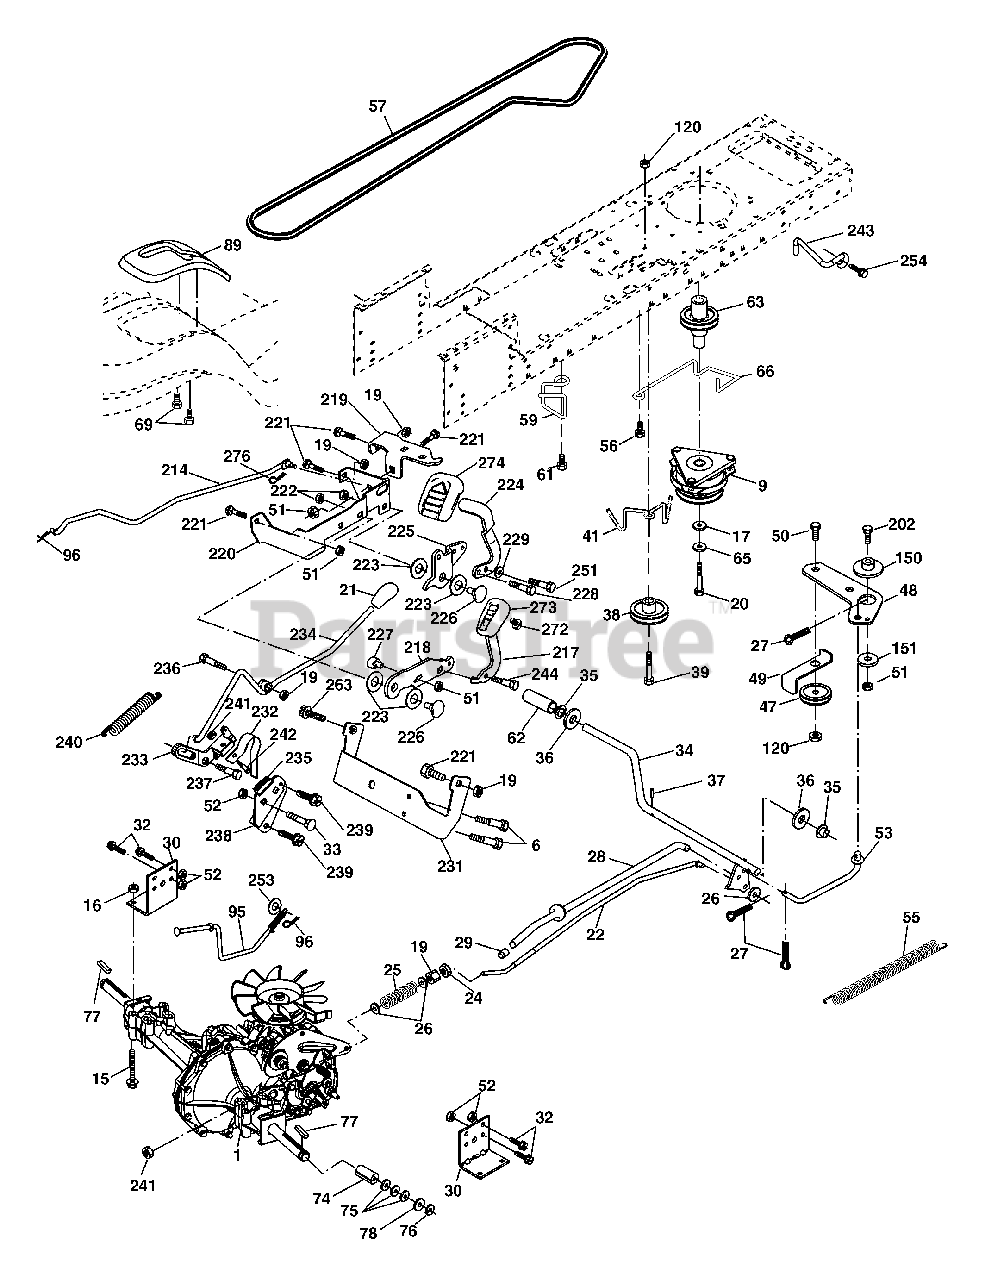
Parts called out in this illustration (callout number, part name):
1	Transaxle
6	Screw 5/16-18 x 3/4
9	Clutch Elec
15	Bolt Hex Flghd 5/16-18 Gr. 5
16	Nut Lock Hex W/Ins. 5/16-18 unc
17	Washer 1-1/2 OD x 15/32 ID x .250
19	Nut Lock Hex W/Wsh 3/8-16 unc
20	Bolt Hex 7/16-20 x 4 x Gr. 5-1.5
21	Knob Custom Control Cruise
22	Rod, Brake
24	Nut, Hex Jam 3/8-16 unc
25	Spring, Brake Rod
26	Washer
27	Pin Cotter 1/8 x 3/4 CAD.
28	Rod, Parking Brake
29	Cap, Brake, Park
30	Bracket, Transaxle
32	Bolt Hex Hd 5/16-18 unc x 3/4
33	Bolt Rdhd Sqnk 5/16-18 unc x 3/4
34	Shaft, Foot Pedal
35	Bearing, Nylon
36	Washer
37	Pin, Roll
38	Pulley, Composite, Flat
39	Bolt Rdhd 3/8-16 x 2- 3/4 Gr. 5
41	Keeper, Belt Idler Flat
47	Pulley, Idler, V-Groove
48	Bellcrank Clutch Grnd Drw Stl
49	Retainer, Belt
50	Bolt
51	Nut Crownlock 3/8-16 unc
52	Nut, Crownlock 5/16-18 unc
53	Link, Clutch
55	Spring, Return, Clutch
56	Screw 3/8-16 x 1-1/4
57	V-Belt, Ground Drive
59	Keeper, Center Span
61	Screw 3/8-16 x .875
62	Cover, Pedal
63	Pulley, Engine
65	Washer
66	Keeper Belt Engine
69	Screw
74	Spacer, Axle
75	Washer 25/32 x 1-1/4 x 16 Ga.
76	E-Ring
77	Key, Square
78	Washer 25/32 x 1-5/8 x 16 Ga.
89	Console, Shift
95	Rod Bypass
96	Retainer Spring 1" Zinc/Cad
120	Nut Lock Flg 3/8-16 unc
150	Spacer Retainer
151	Washer 13/32 x 2 x 10 Ga.
202	Bolt Carr Sh 3/8-16 x 1-3/4 Gr. 5
214	Link Transaxle
217	Pedal Assy, Reverse, with Pad
218	Arm Control Pedal Reverse
219	Bracket Frest Pdl Ctrl. Hyd
220	Bracket Mtg. Pedal Control
221	Bolt Rdhd Sqnk 3/8-16 unc x 3/4
222	Nut Crownlock 7/16-14 unc
223	Washer Nylon 11/16 ID x .060
224	Pedal Forward
225	Arm Control Pedal Forward
226	Bolt Pivot Spacer
227	Cam Reverse Pedal LT
228	Bolt Shoulder 5/16-18
229	Washer Serrated 5/16 x .75
231	Strap Torque
232	Actuator Cruise Disengage
233	Pawl Control Cruise
234	Lever Control Cruise
235	Sector Control Cruise
236	Bolt Shoulder 3/8-16 unc 1/44
237	Bolt Shoulder 5/16-18
238	Arm Mtg. Cruise Sector
239	Screw Thdrol 5/16 x 1/2
240	Spring Return Cruise Control
241	Nut Centerlock 1/4-20 unc
242	Bolt Fin Hex 1/4-20 unc x .75
243	Bracket Anti-Rotation CVX
244	Screw 5/16-18 x 5/8
251	Screw 5/16-18 x 1
253	Washer .3125 x .615 x 16 Ga.
254	Screw 3/8-16 x 1
263	Screw 3/8-16 x 3/4
272	Screw, 5/16-18 x 1/2 TT
273	Pad, Reverse Pedal
274	Cover Pedal Forward
